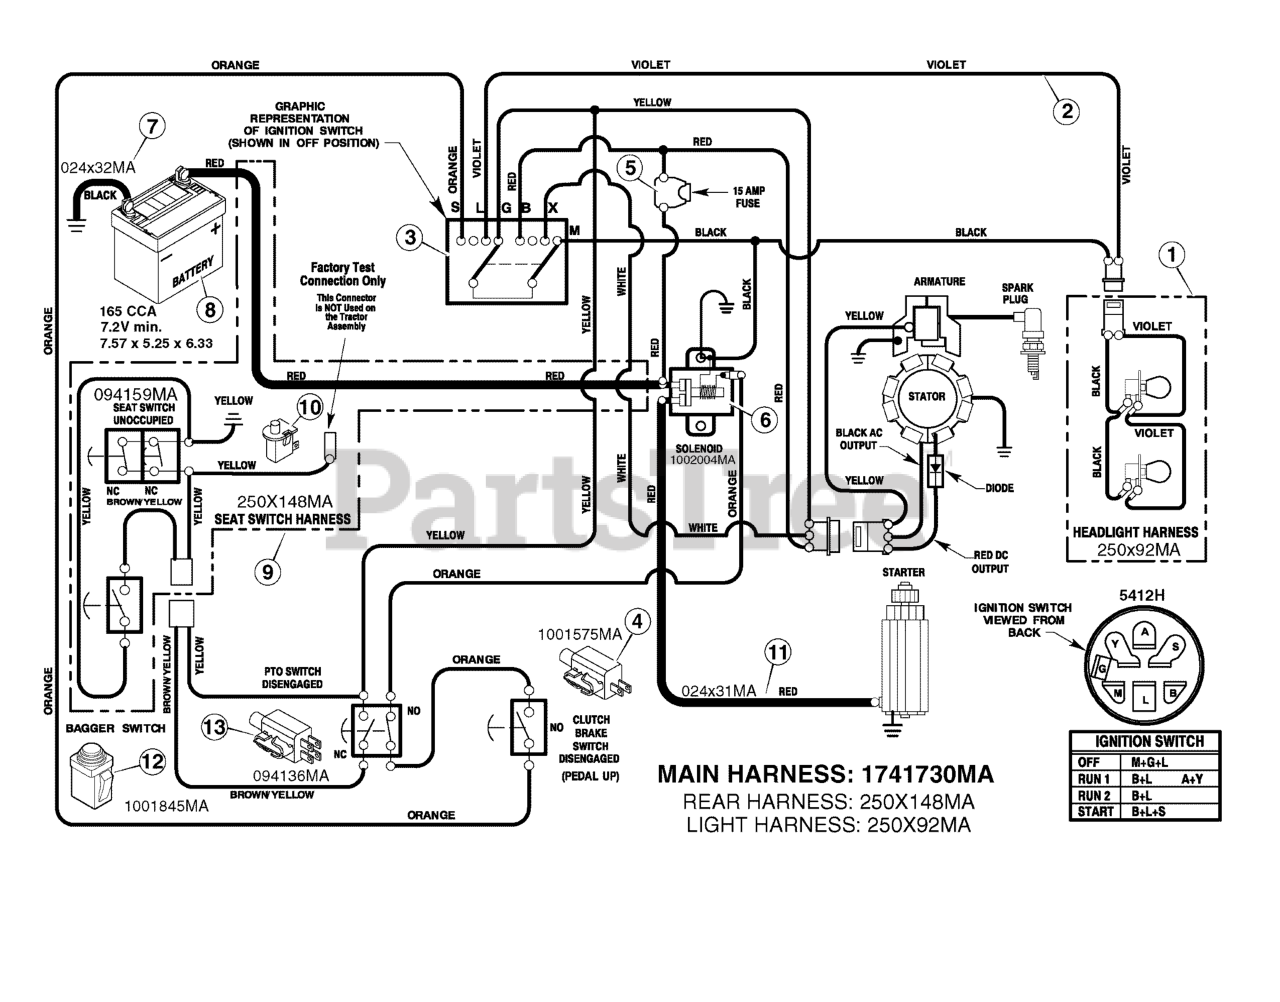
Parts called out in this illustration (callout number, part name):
1	HARNESS, Light Wire
2	HARNESS, Chassis Wire
3	SWITCH, Ignition
4	SWITCH, Limit
6	SOLENOID
7	CABLE, Battery Ground
8	BATTERY
9	HARNESS, Seat Switch Wire
10	SWITCH, Seat Sensor
12	SWITCH, Bag Sensor
13	SWITCH, Limit
